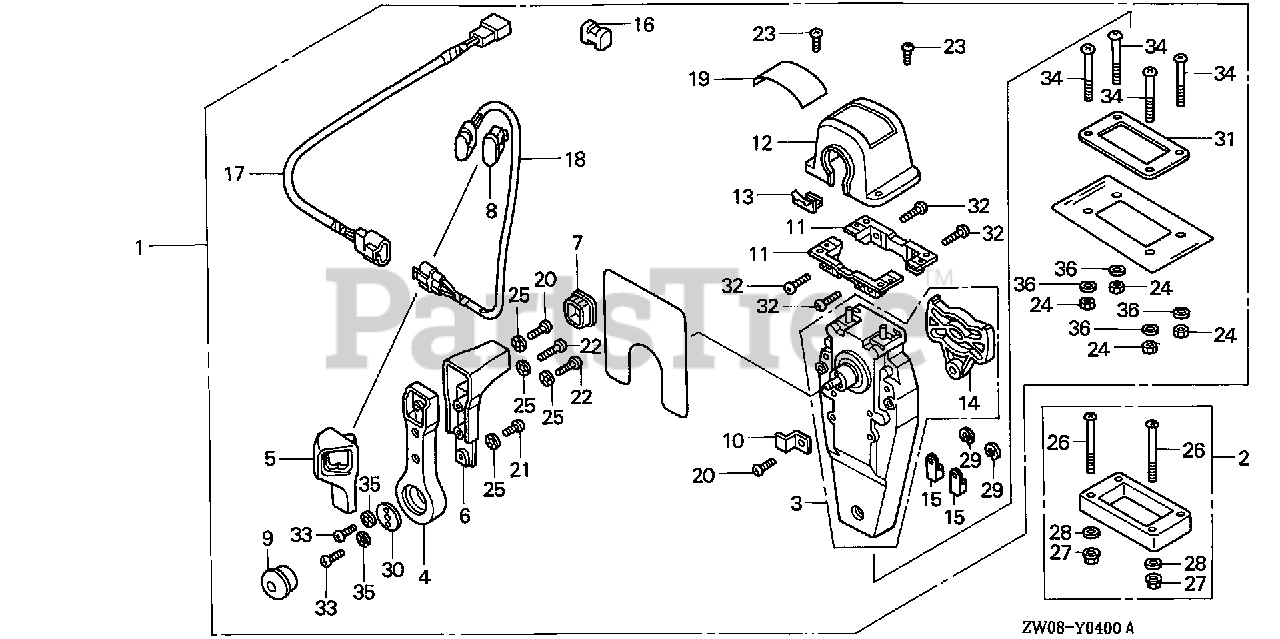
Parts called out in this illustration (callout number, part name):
1	BOX KIT, R. REMOTE CONTROL (TOP MOUNT SINGLE)
2	SPACER KIT, REMOTE CONTROL BOX (TOP MOUNT SINGLE)
3	HOUSING ASSY., L. (INNER) (TOP MOUNT)
4	HANDLE, REMOTE CONTROL
5	COVER, L. GRIP
6	GRIP, REMOTE CONTROL HANDLE
7	CAP, GRIP
8	CAP, SWITCH
9	BUTTON, THROTTLE
10	PLATE, CABLE CLAMP
11	BRACKET, REMOTE CONTROL HOUSING
12	HOUSING, REMOTE CONTROL BOX
13	HOUSING, LEAD
14	PLATE, DWELL
15	TERMINAL, CABLE
16	SPACER, CABLE CLAMP
17	SUB-HARNESS ASSY., POWER TRIM-TILT (A)
18	SWITCH ASSY., POWER TRIM-TILT (A)
19	MARK, REMOTE CONTROL (SINGLE)
20	SCREW, PAN (5X16)
21	SCREW, PAN (5X10)
22	SCREW, PAN (5X20)
23	SCREW, PAN (4X10)
24	NUT, HEX. (5MM)
25	WASHER, LOCK (5MM)
26	SCREW, PAN (5X65)
27	NUT, FLANGE (5MM)
28	WASHER, PLAIN (5MM)
29	E-RING (6MM)
30	PLATE, HANDLE
31	GASKET, SINGLE
32	SCREW, PAN (5X18)
33	SCREW, PAN (6X18)
34	SCREW, PAN (5X40)
35	WASHER, LOCK (6MM)
36	WASHER, PLAIN (5MM)
